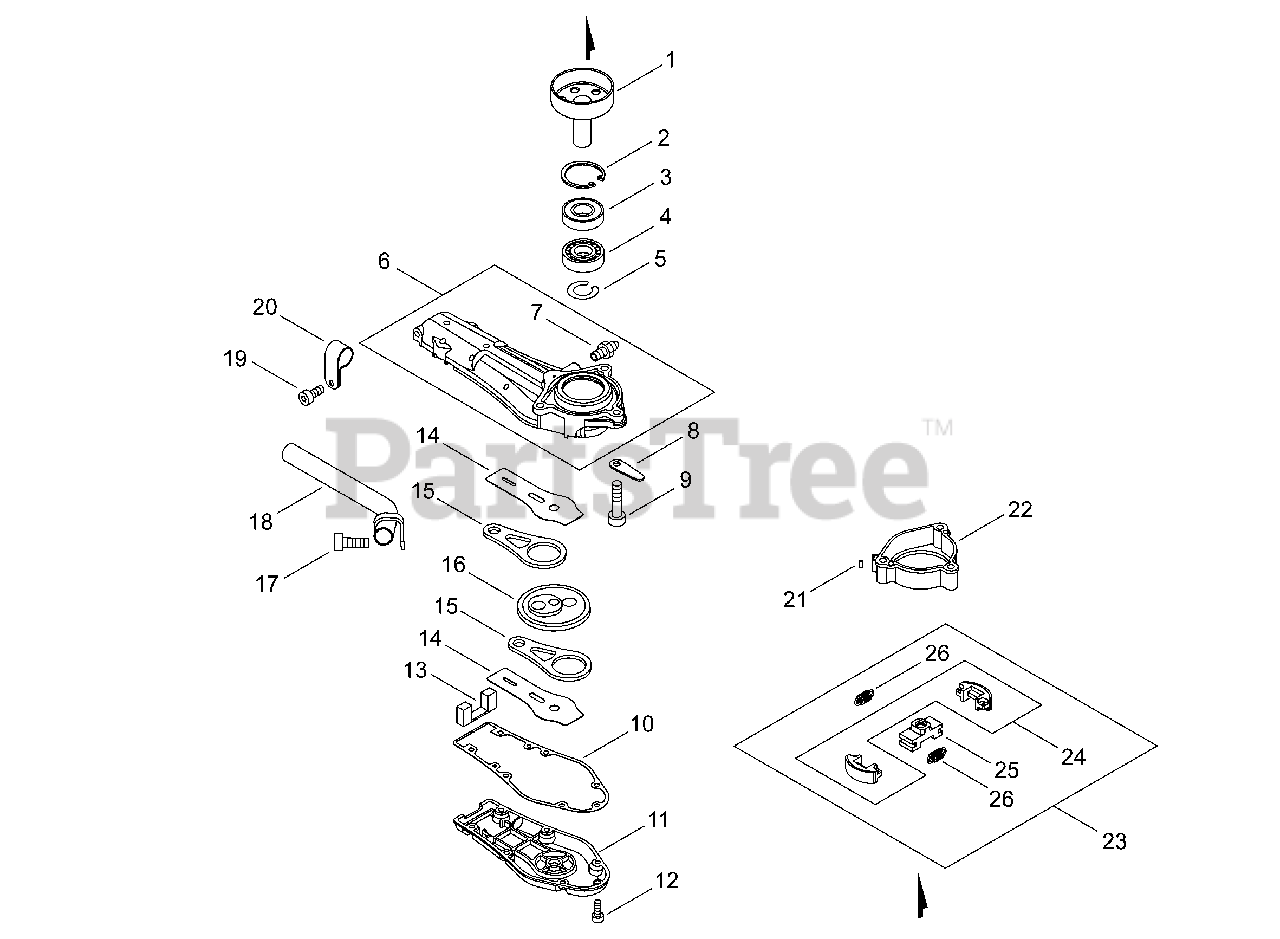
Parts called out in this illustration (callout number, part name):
1	DRUM, CLUTCH
2	RING, SNAP 35
3	BEARING, BALL 6202 DDU
4	BEARING, BALL 6202
5	RING, SNAP 14
6	CASE, GEAR
7	FITTING, GREASE
9	BOLT, TORX 6
10	GASKET, GEAR CASE
11	COVER, GEAR CASE
12	BOLT, TORX 4×16
14	PLATE, EYE
15	ROD, CONNECTING
16	GEAR, SPUR
17	BOLT, TORX 5×10
18	PIPE, EXHAUST
19	BOLT, TORX 4×10
20	SUPPORT, PIPE
21	NUT M5
22	CASE, CLUTCH
23	CLUTCH ASSY
24	SHOE SET, CLUTCH
25	HUB, CLUTCH
26	SPRING, CLUTCH
